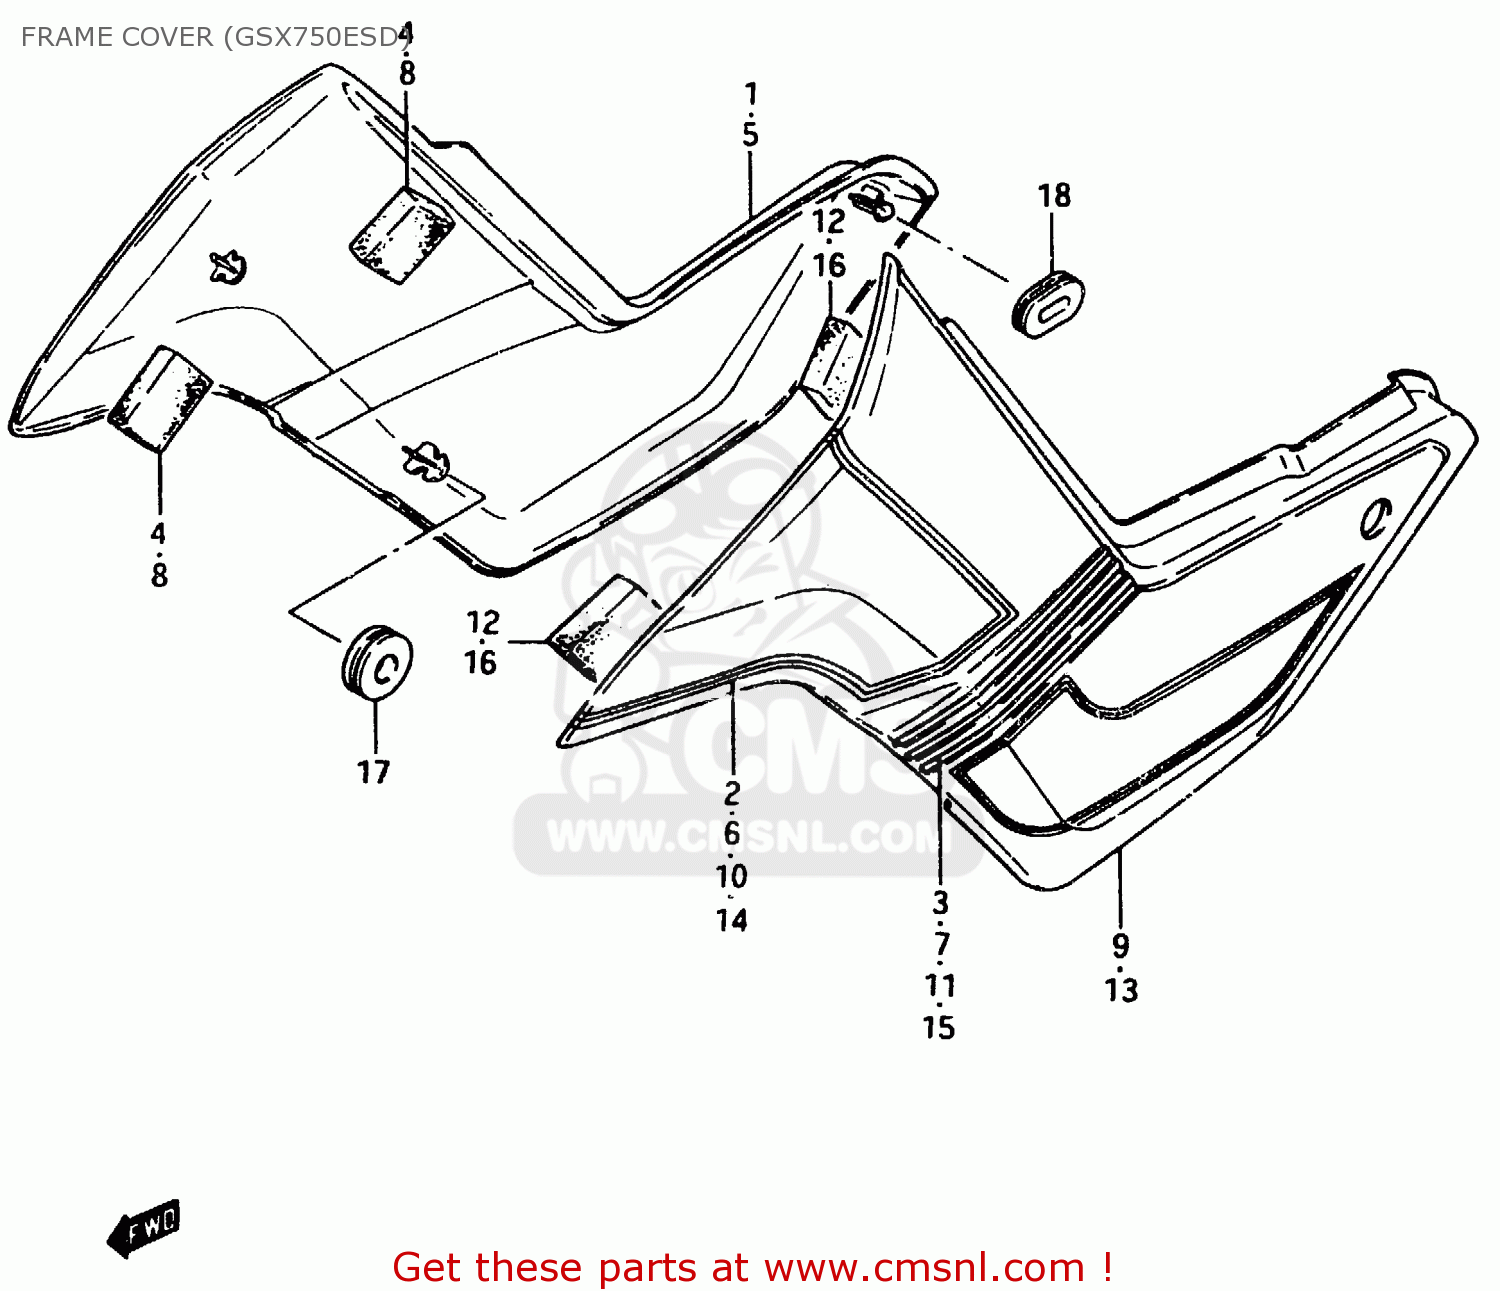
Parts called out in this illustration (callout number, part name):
1	COVER, FRAME RH
2	TAPE SET, FRAME COVER RH
3	DENT,FRAME COVER,RIGHT
4	CUSHION
5	COVER,FRAME,R
6	TAPE SET, FRAME COVER RH
7	DENT,FRAME COVER,RIGHT
8	CUSHION
9	COVER, FRAME LH
10	TAPE SET, FRAME COVER LH
11	DENT,FRAME COVER,LEFT
12	CUSHION
13	COVER, FRAME LH
14	TAPE SET, FRAME COVER LH
15	DENT,FRAME COVER,LEFT
16	CUSHION
17	CUSHION
18	CUSHION
